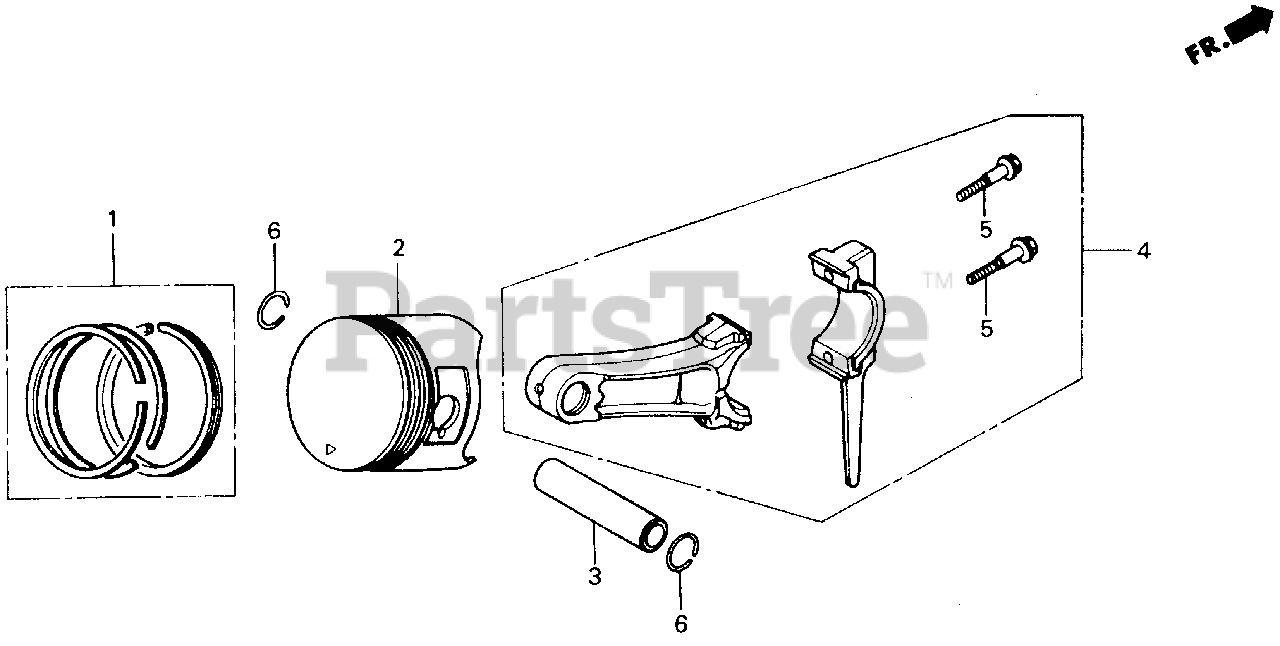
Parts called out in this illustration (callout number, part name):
1	RING SET, PISTON (STD) (NIPPON)
1	RING SET, PISTON (0.25)
1	RING SET, PISTON (0.50)
1	RING SET, PISTON (0.75)
2	PISTON (STD)
2	PISTON (0.25)
2	PISTON (0.50)
2	PISTON (0.75)
3	PIN, PISTON
4	ROD ASSY., CONNECTING (STD)
4	ROD ASSY., CONNECTING
5	BOLT, CONNECTING ROD
6	CLIP, PISTON PIN (20MM)
